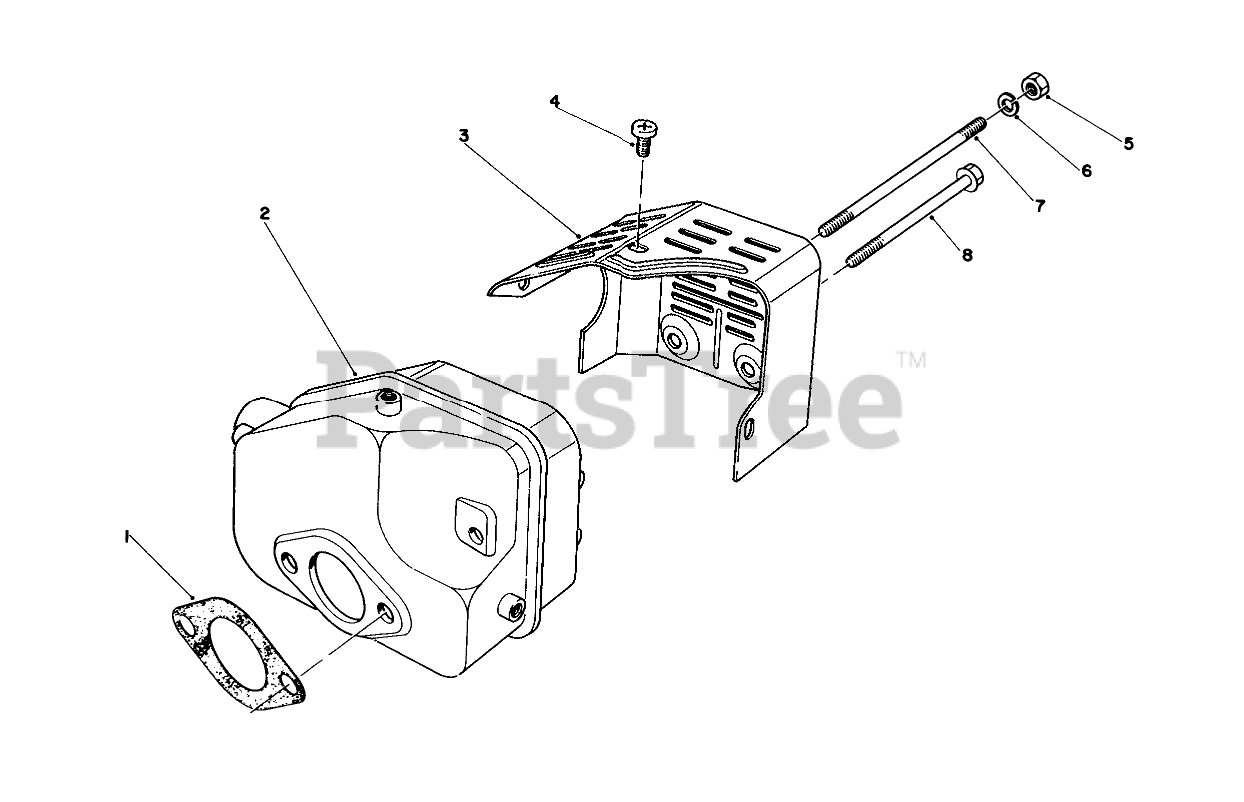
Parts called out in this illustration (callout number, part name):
1	GASKET
2	Muffler
3	COVER
4	SCREW
6	WASHER-LOCK
